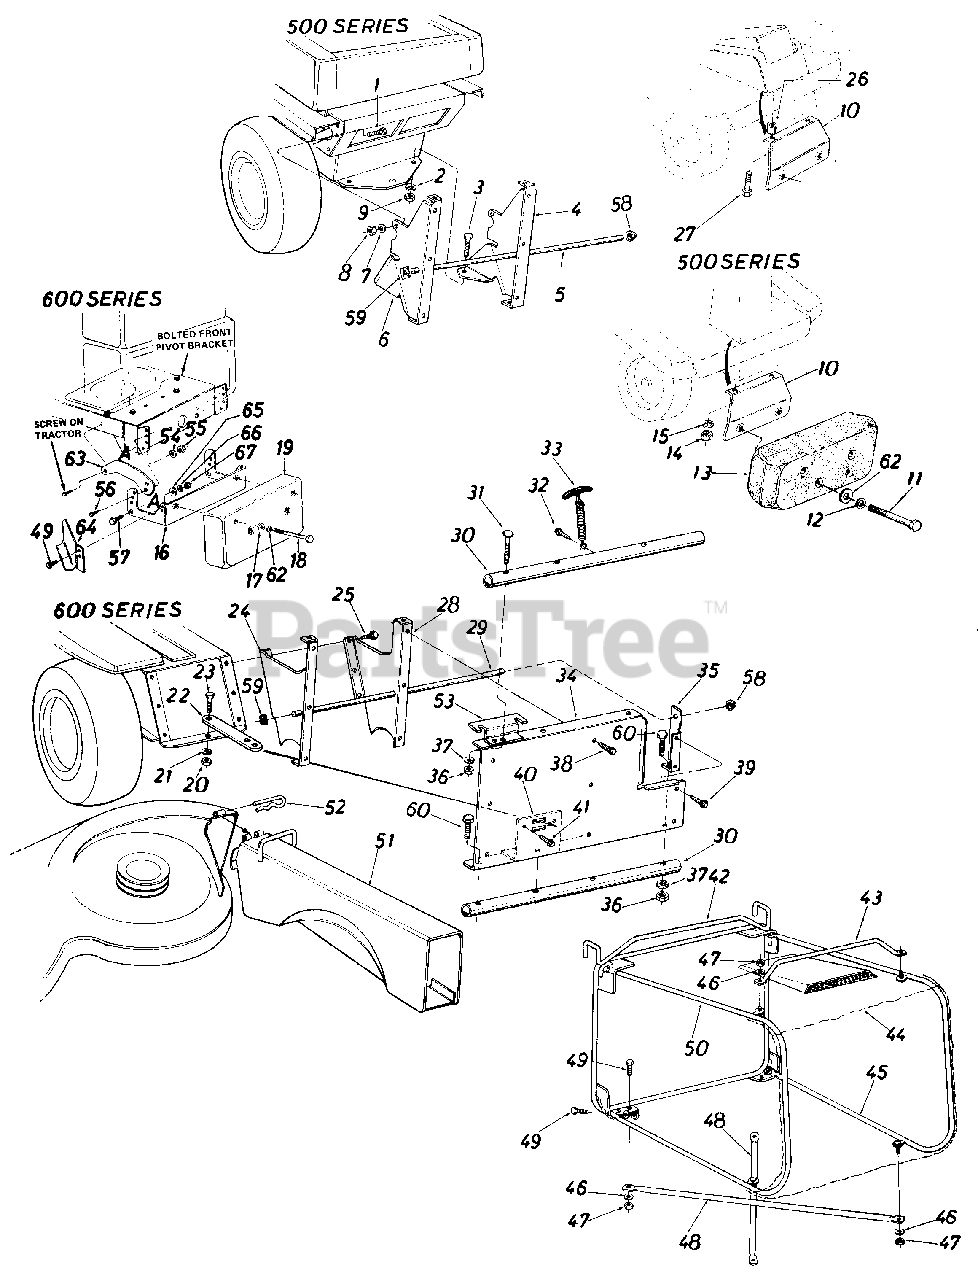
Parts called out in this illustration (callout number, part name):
1	Hex Bolt 5/16-18 x 1.00" Lg. *
2	L.-Wash. 5/16" I.D.*
3	Hex Bolt 5/16-18 x 1.00" Lg.*
4	CatcherSupport Brkt-R.H.
7	L.-Wash. 5/16" I.D.*
8	Hex Nut 5/16-18 Thd.*
9	Hex Nut 5/16-18 Thd.*
10	Counterweight Bracket
11	Hex Bolt 3/8-16 x 4.5" Lg.*
12	Belleville Wash. .400" I.D. x.88" O.D.
13	Front Counterweight 381bs.
14	Hex Nut5/16-18 Thd.*
15	L.-Wash. 5/16" I.D.*
16	Counterweight Bracket
17	Belleville Wash. .400" I.D. x.88" O.D.
18	Hex Bolt 3/8-16 x 4.5" Lg.*
19	Front Counterweight 38 Ibs.
20	Hex Jam Nut 1/2-13 Thd. *
21	L.-Wash. 1/2" I.D.*
24	Catcher Support Brk't.-L.H.
25	Hex Wash. Hd. Self Tap Scr. 5/16-18 x .75 Lg.*
26	Spacer.380" I.D. x 1.00" O.D. x.320" Lg.
27	Not Part of Kit
28	Catcher Support Brk't.-R.H.
31	Curved Carriage Bolt 5/16-18 x 1.75" Lg.
32	Hex "AB"-Tap Scr. 1/4" x .62" Lg.
33	Hood Latch Ass'y.
34	Grass Catcher Adapter
35	Grass Catcher Support Brk't.-R.H.
36	Hex Nut 5/16-18 Thd.*
37	L.-Wash. 5/16" I.D.*
38	Hex Wash. Hd. Self Tap Scr. 1/4-20x.50" Lg.
39	Hex Wash. Hd. Self Tap Scr. 1/4-20 x .50 " Lg .
40	Hitch Bracket
41	Hex Wash. Hd. Self Tap Scr. 1/4-20 x .50" Lg.
42	Grass Bag Frame Ass'y.
43	Grass Catcher Handle 26.75
44	Grass Catcher Bag
47	Hex L.-Nut 1/4-2 Thd.
48	Bottom Cross Brace 30.36" Lg.*
49	Hex Bolt 1/4-20 x .62" Lg. *
52	Not Part of Kit
53	Grass Catcher Support Plate
54	L.-Wash. 7/16" I.D.*
55	Hex Nut 7/16-14 Thd.*
56	Truss Mach. Scr. 5/16-18 x .75" Lg.
57	Hex Bolt 7/16-14 x 1.00" Lg.*
58	Push Cap
59	Speed Nut
60	Hex Bolt 5/16-18 x 1.75" Lg.*
62	Fl.-Wash. .390" I.D. x 1.12" O.D. x .187 Thk.
63	Tie Strap
64	Exhaust Deflector
65	Fl-Wash. .28" I.D. x .50" O.D.
66	L-Wash. 1/4" I.D.*
67	Hex Nut 1/4-20 Thd.
